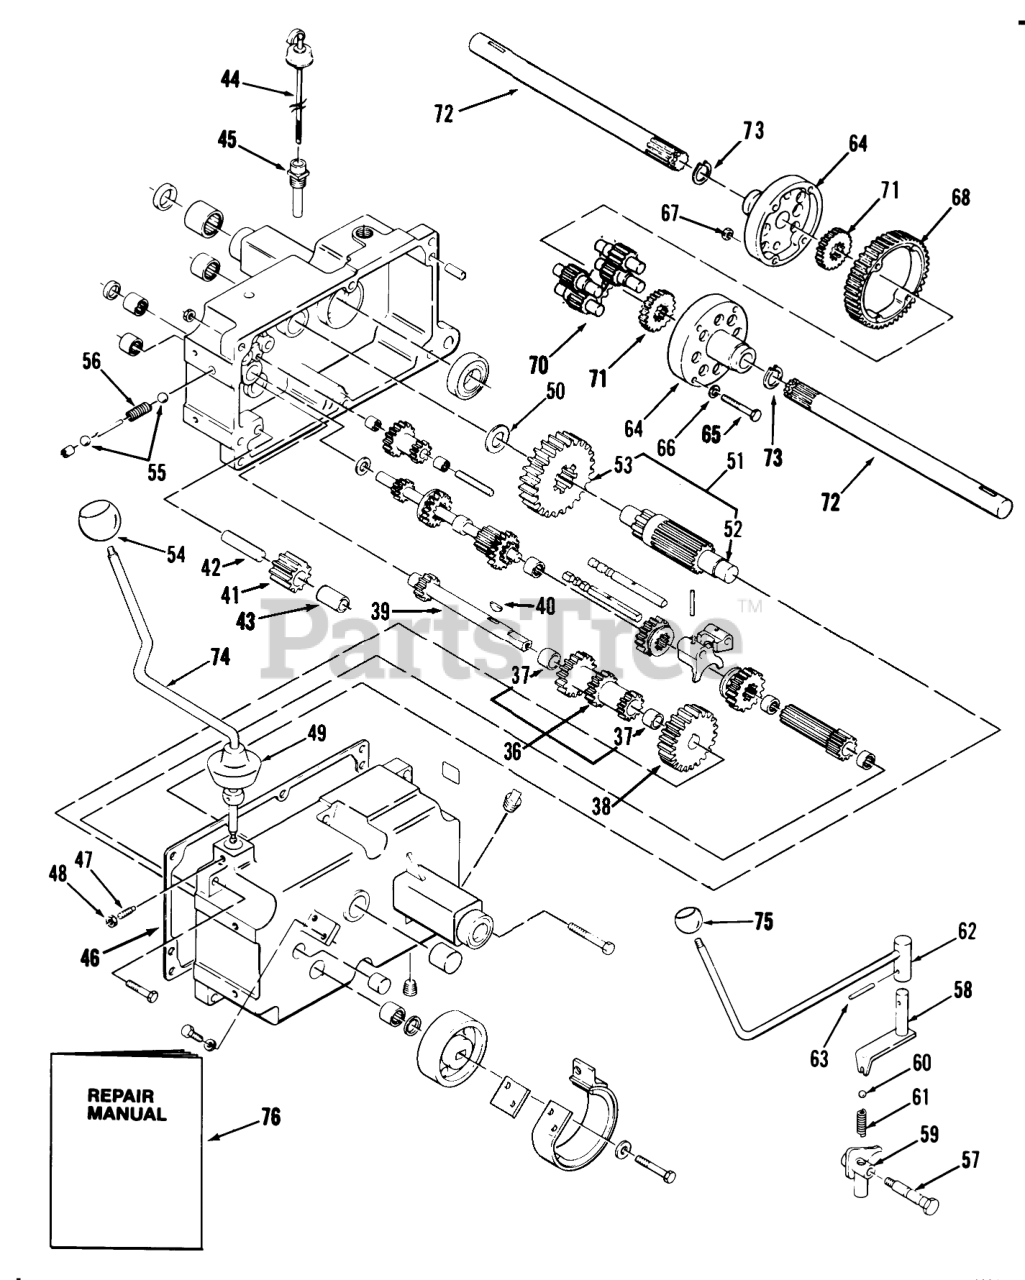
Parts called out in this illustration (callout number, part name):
36	GEAR-CLUSTER
37	BUSHING-BRONZE
38	GEAR-CLUSTER SHAFT
39	Cluster Shaft
40	KEY-WOODRUFF
41	GEAR/BUSHING ASM-REVERSE IDLER
42	PIN-DIFFERENTIAL
43	BUSHING
44	ASSY-DIPSTICK
45	NIPPLE-TRANS FILL
46	GASKET-TRANSMISSION
47	SETSCREW
48	Nut
49	COVER-DUST
50	WASHER-THRUST
51	GEAR ASM
52	PINION SHAFT
55	BALL-DETENT
56	SPRING-SHIFT STOP
57	BOLT-DETENT
58	SHIFT ASM
59	Shift Fork
60	BALL-DETENT
61	SPRING-SHIFT STOP
62	SHIFT ROD ASM
63	PIN-SPIROL
64	END CAP-DIFFERENTIAL
65	Bolt 3/8-16 x 3 1/4
66	WASHER
68	DIFFERENTIAL BULL GR
70	GEAR-PINION, 11T
71	AXLE GEAR
72	AXLE-REAR
73	Snap Ring
74	ASM-Rod
75	Knob
76	MANUAL
